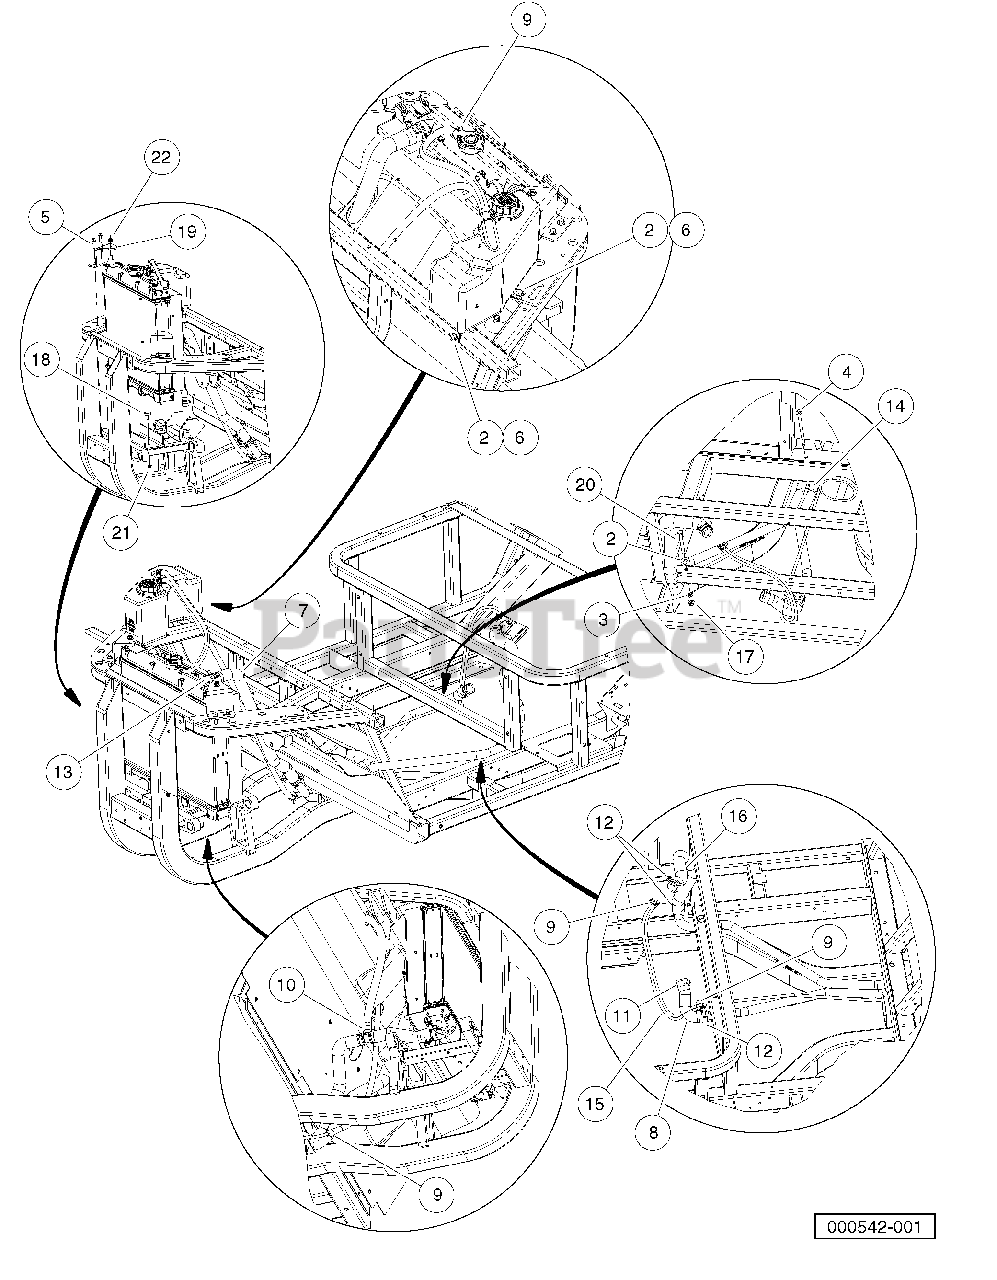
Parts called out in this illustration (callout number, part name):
1	Instl, Cooling Sys, Diesel
2	Washer, 5/16 Type B Flat
3	Spacer, 0.720"
4	Bolt-hex Fl, M8 X 1.25 X 135
5	Screw, M8X1.25X30, Hex
6	M8-1.25x20 Taptite
7	Hose, Coolant Upper Rad
8	Hose, Coolant Lower Eng
9	Clamp, Hose, CTB 15mm
10	Clamp, Hose, CTB 22mm
11	Clamp, Hose, Ctb 30mm
12	Clamp, Hose, Ctb 35mm
13	Clamp, Hose, Ctb 38mm
14	Clamp, Bar
15	Hose, Vent Tube To Eng, Coolnt
16	Hose, Coolant, Return, Engine
17	Lock Nut, Flg M8 X 1.25 Nylon
18	Bumper, 19mm Stud
19	Bracket, Radiator Support
20	Bolt, M8 X 1.25 X 110
21	Nut Flg, M6 X 1 Serrated
22	Nut Flg, M8 X 1.25 Serrated
